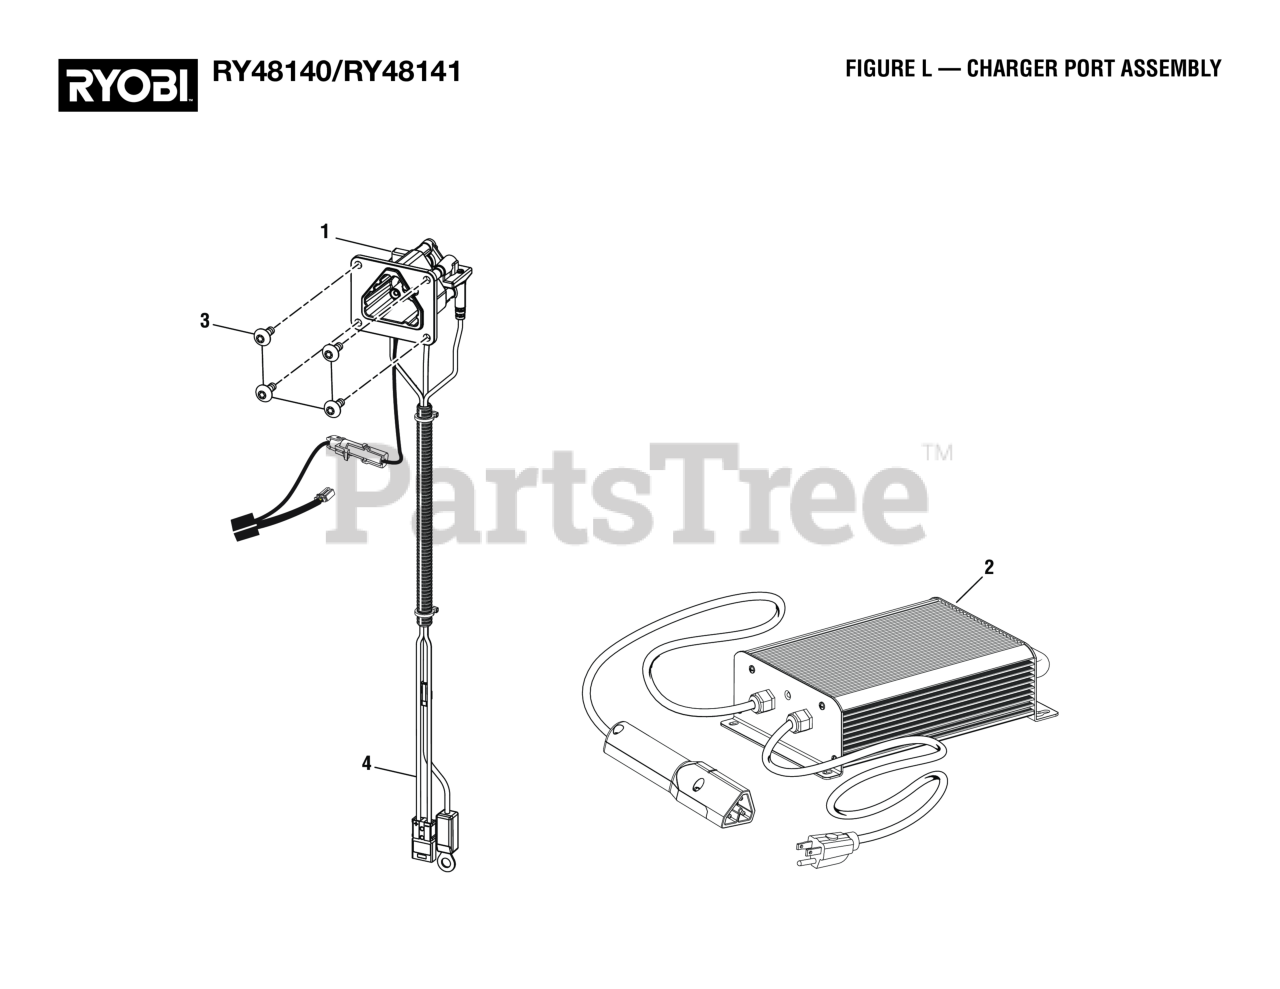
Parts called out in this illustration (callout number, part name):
1	Charger Receptacle
2	American Standand Charger
3	Screw (M6 x 10 mm, Soc. Button Hd.)
4	Battery Temperature Sensor
